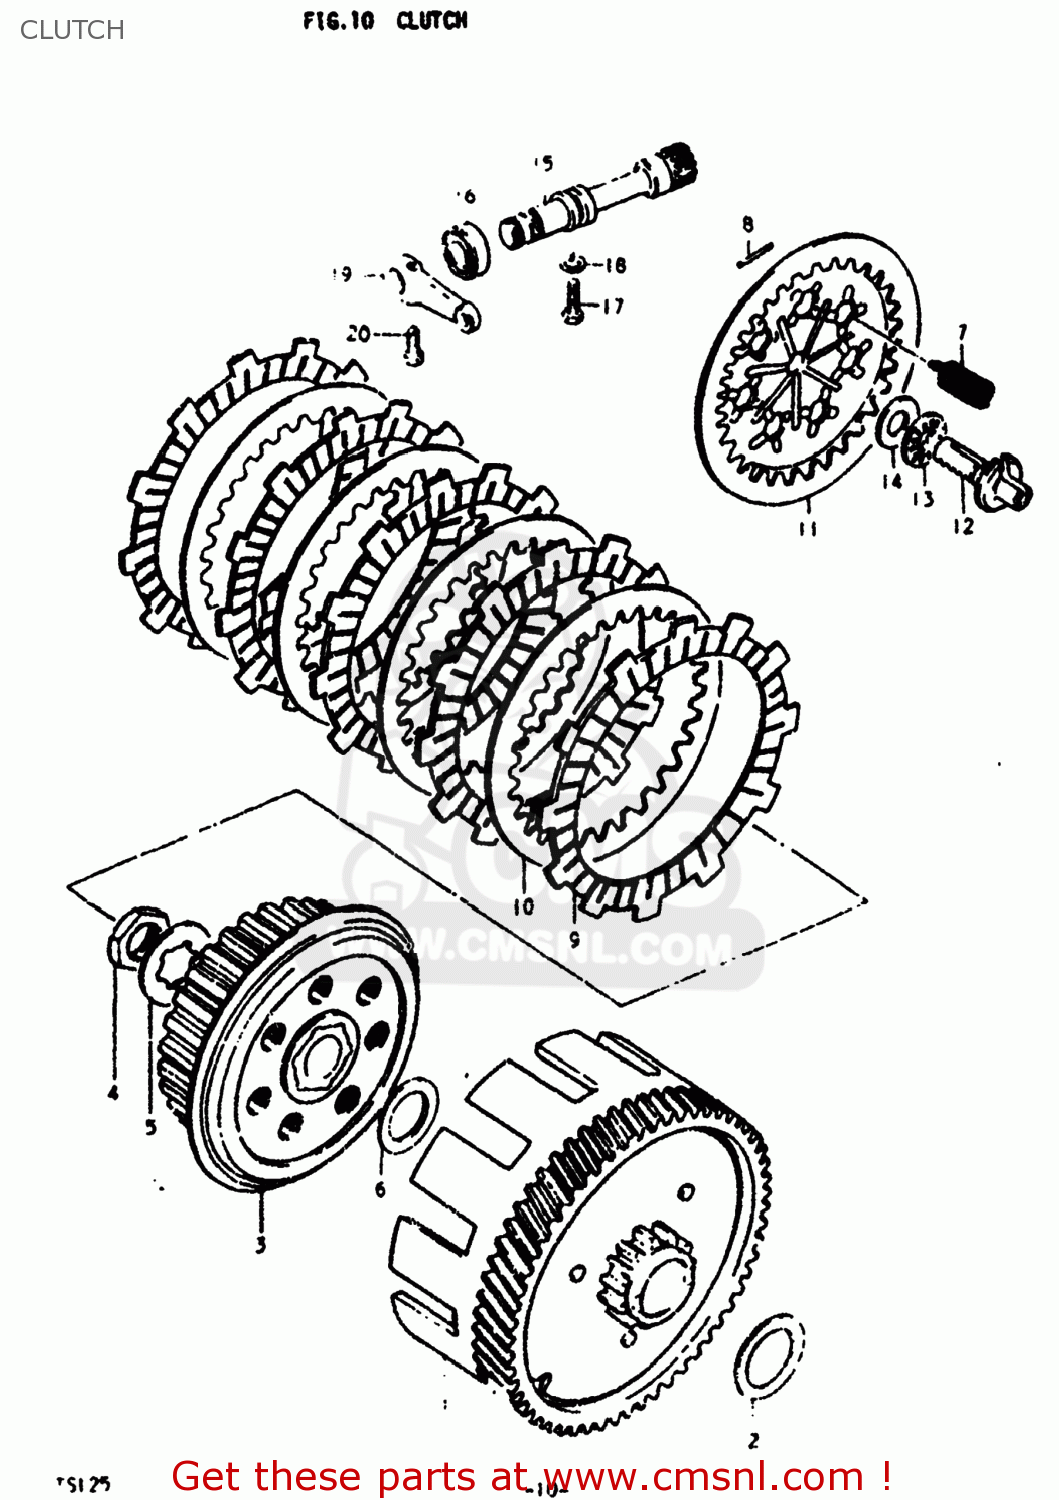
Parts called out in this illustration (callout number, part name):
1	GEAR ASSEMBLY,PRIMARY DRIVE
2	WASHER
3	HUB,CLUTCH SLEEVE
4	NUT
5	WASHER,LOCK
6	WASHER
7	SPRING
8	PIN(2.5X19.8)
9	PLATE,CLUTCH DRIVE
10	PLATE,CLUTCH DRIVEN (NAS)
11	PLATE,CLUTCH PRESSURE
12	BACK,CLUTCH RELEASE
13	BEARING(10X22X2.8)
14	WASHER(10.1X21.4X0.8)
15	PINION,CLUTCH RELEASE
16	OIL SEAL
17	BOLT(6X12)
18	WASHER
19	ARM,CLUTCH RELEASE
20	BOLT
